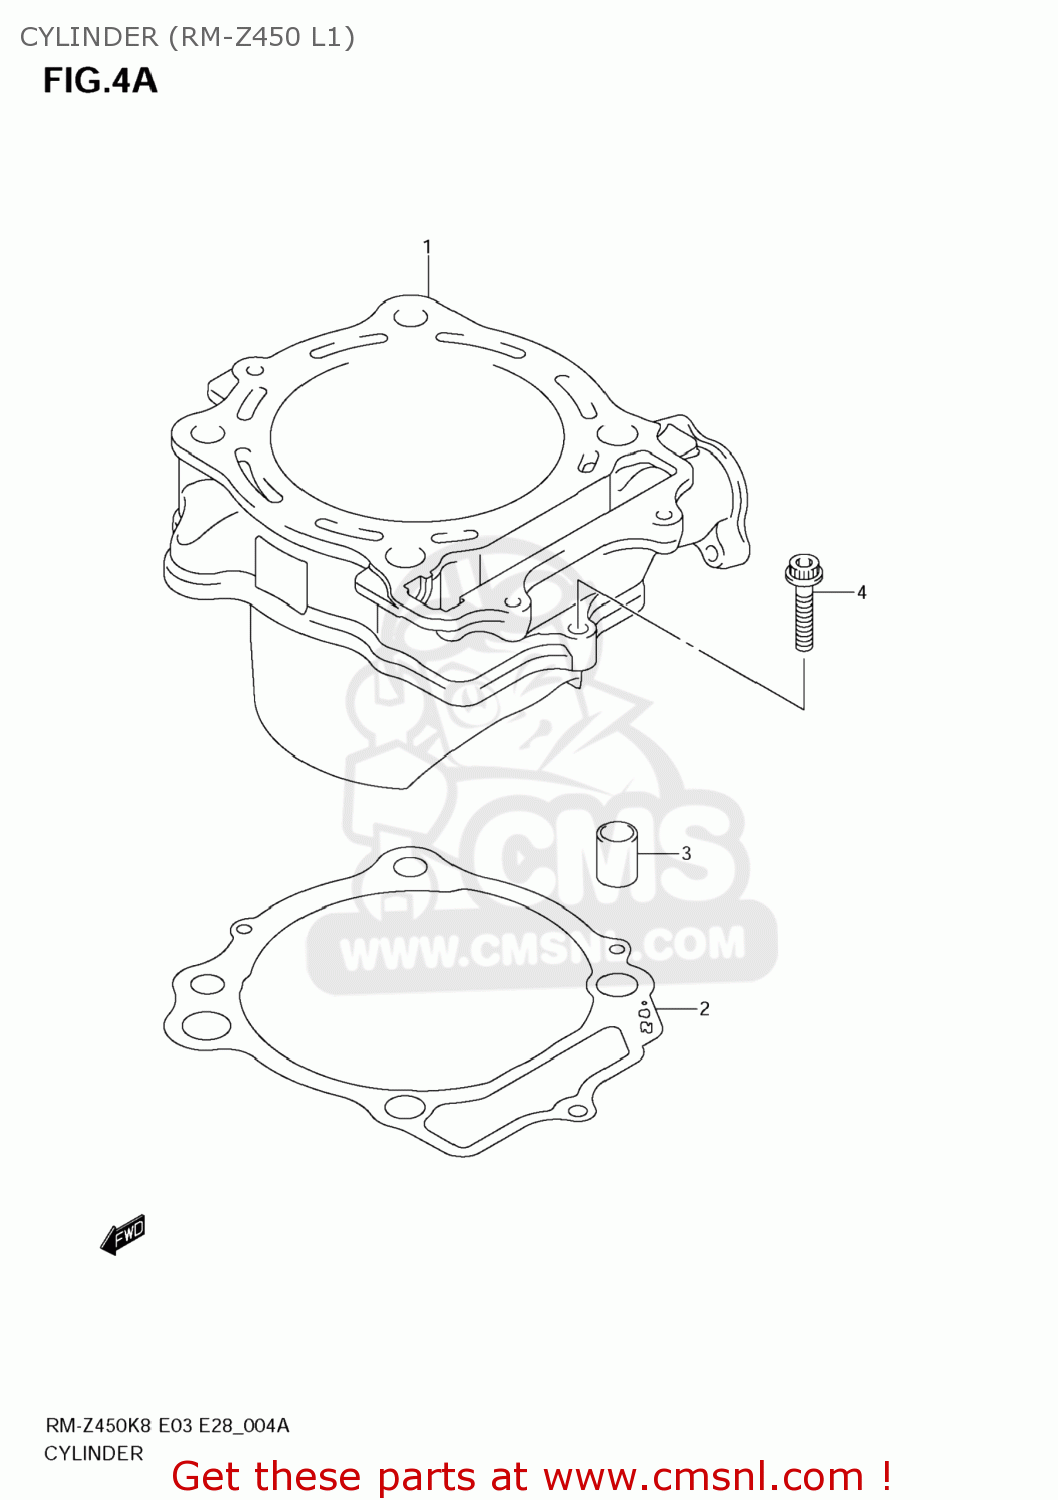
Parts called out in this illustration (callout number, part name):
1	CYLINDER
2	GASKET,CYLINDER (NAS)
3	PIN
4	BOLT
